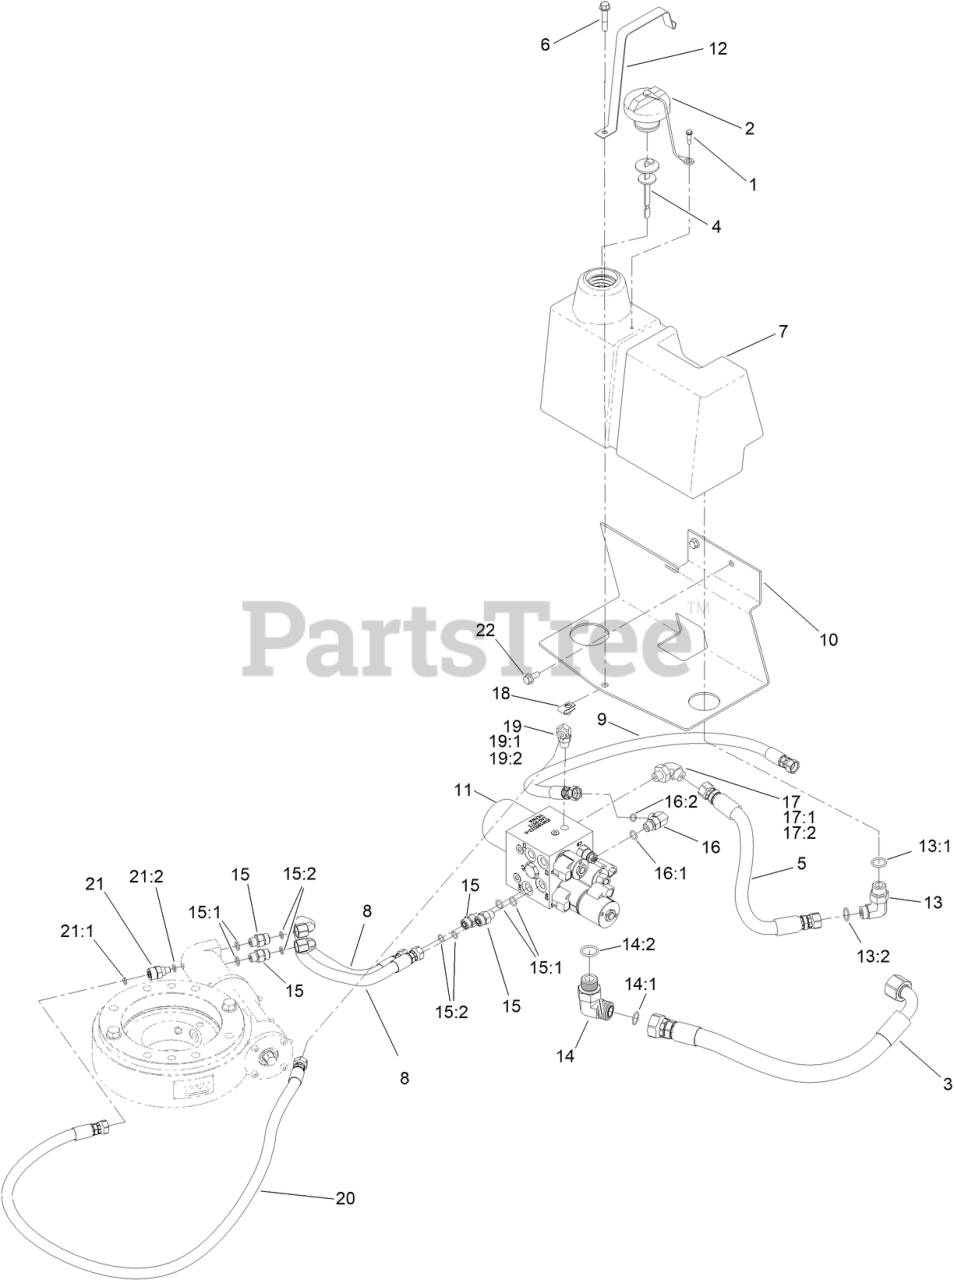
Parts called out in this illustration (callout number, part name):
1	SCREW-SHOULDER
2	CAP-OIL, HYD
3	HOSE ASM
4	DIPSTICK ASM
5	HOSE-HYD
6	SCREW-HWH
7	RESERVOIR-OIL, HYD
8	HOSE-HYDRAULIC
9	HOSE ASM
10	SUPPORT - TANK, HYD
11	MANIFOLD-HYDRAULIC ASM
12	STRAP-HYDRAULIC TANK
13	FITTING-ELBOW, 90 DEG
13:1	O-RING
13:2	O-RING
14	FITTING-ELBOW-90
14:1	O-RING
14:2	O-RING
15	FITTING-STRAIGHT
15:1	O-RING
15:2	O-RING
16	FITTING-ELBOW, 90 DEG
16:1	O-RING
16:2	O-RING
17	FITTING-HYD, 90 DEG
17:1	O-RING
17:2	O-RING
18	NUT-U
19	FITTING-ELBOW, 90 DEG
19:1	O-RING
19:2	O-RING
20	HOSE-HYDRAULIC
21	ADAPTER-HYD, STRAIGHT
21:1	O-RING
21:2	O-RING
22	SCREW-HHF
